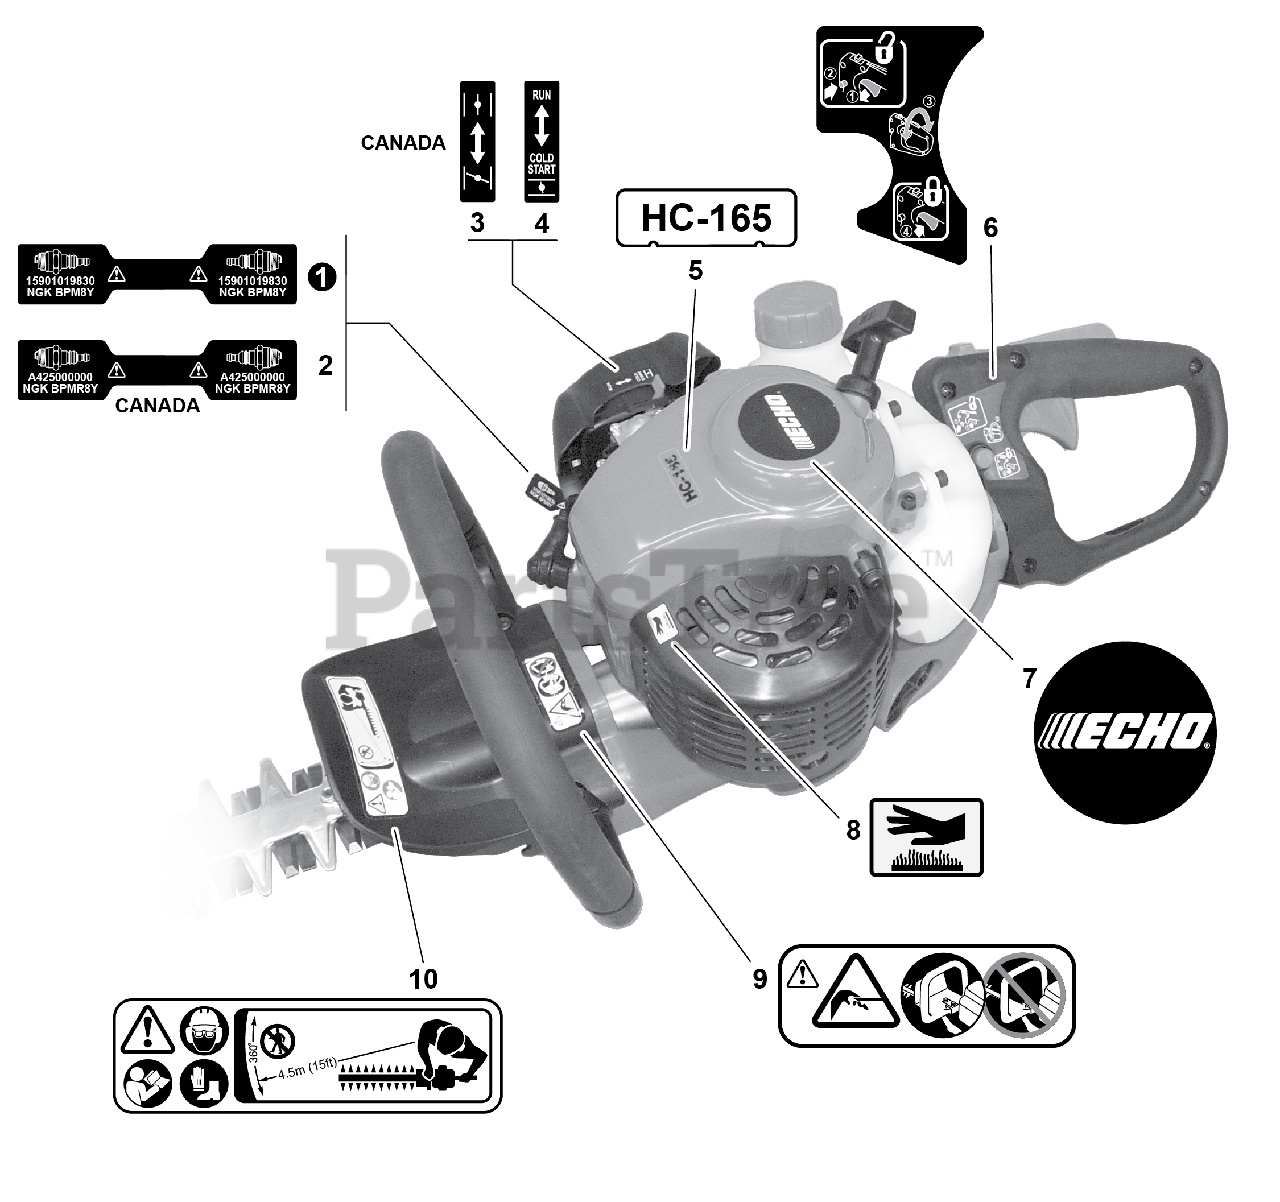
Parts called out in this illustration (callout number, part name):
1	LABEL - SPARK PLUG -- BPM8Y
2	LABEL - SPARK PLUG -- BPMR8Y
3	LABEL - CHOKE
4	LABEL - CHOKE
5	LABEL - MODEL -- HC-165
6	LABEL - CAUTION -- OPERATION
7	LABEL - ECHO
8	LABEL - HOT SURFACE
9	LABEL - CAUTION
10	LABEL - CAUTION
